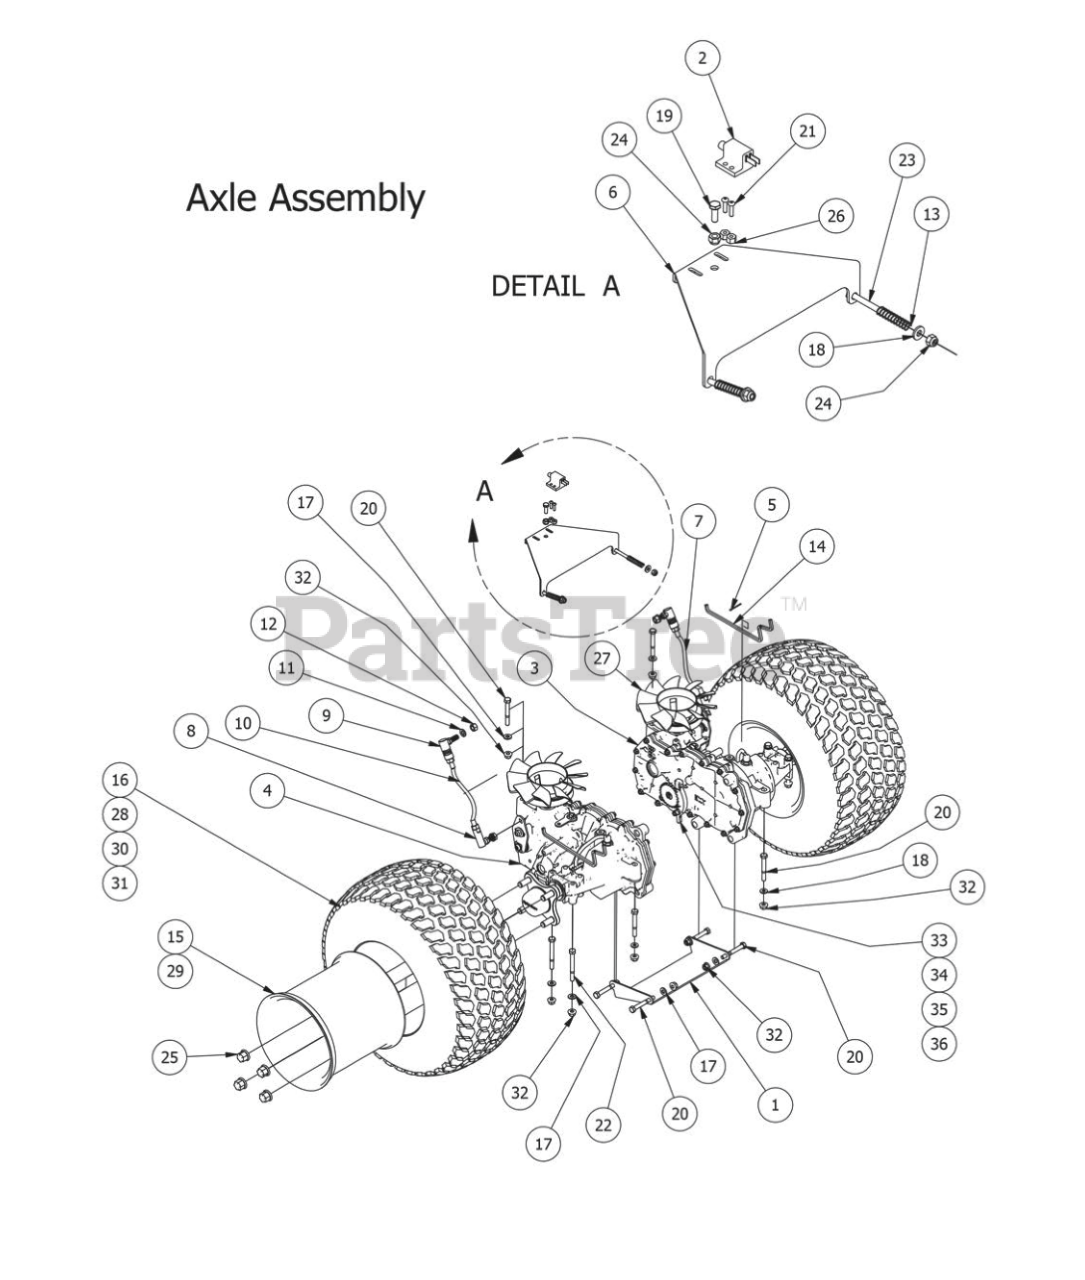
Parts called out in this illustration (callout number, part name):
1	MZ Transaxle Support (Lower)
2	Safety Switch
3	EZT - Right MZ Models
4	EZT- Left MZ Models
5	Cotter Pin-Brake bar on Mz
6	MZ Brake Lock Bracket
7	Steering linkage for Mz Left
8	3/8-24 Ball Joint
9	Quick Release Ball Joint
10	Steering linkage for Mz right
11	3/8" Lock Washer
12	3/8" Fine Threaded Jam Nut
13	Brake Spring
14	MZ Brake Release Bar
15	Rear rim for a 48 & 54"
16	18 x 9.50 -8 Tire Only MZ 48 &54" Deck only
17	5/16" Flat Washer
18	1/4" Flat Washer
19	1/4" x 3/4" Hex Bolt
20	5/16" x 2 1/2" Bolt
21	10-24 X 5/8 BS C/S 18-8 SS
22	5/16" x 3" Hex Bolt
23	1/4-20 x2-1/2 Gr2 hex C/s zir
24	1/4" Nylock Nut
25	Acorn Lug Nut
26	10-24 Nylon Insert Locknut
27	MZ Fan & Pulley Kit
28	42" MZ 18x 7.50-8 tire only
29	Rear rim only 42" MZ
30	18x9.50-8 48 & 54" Deck Tire and Wheel Assembly
31	18x8.50-8/8" 42" Deck Tire and Wheel Assembly
32	5/16" Nylon Flange Nut
33	MZ Brake Cog Kit
34	MZ Retainer Ring for Brake
35	MZ Brake Gear
36	MZ Brake Arm Kit
